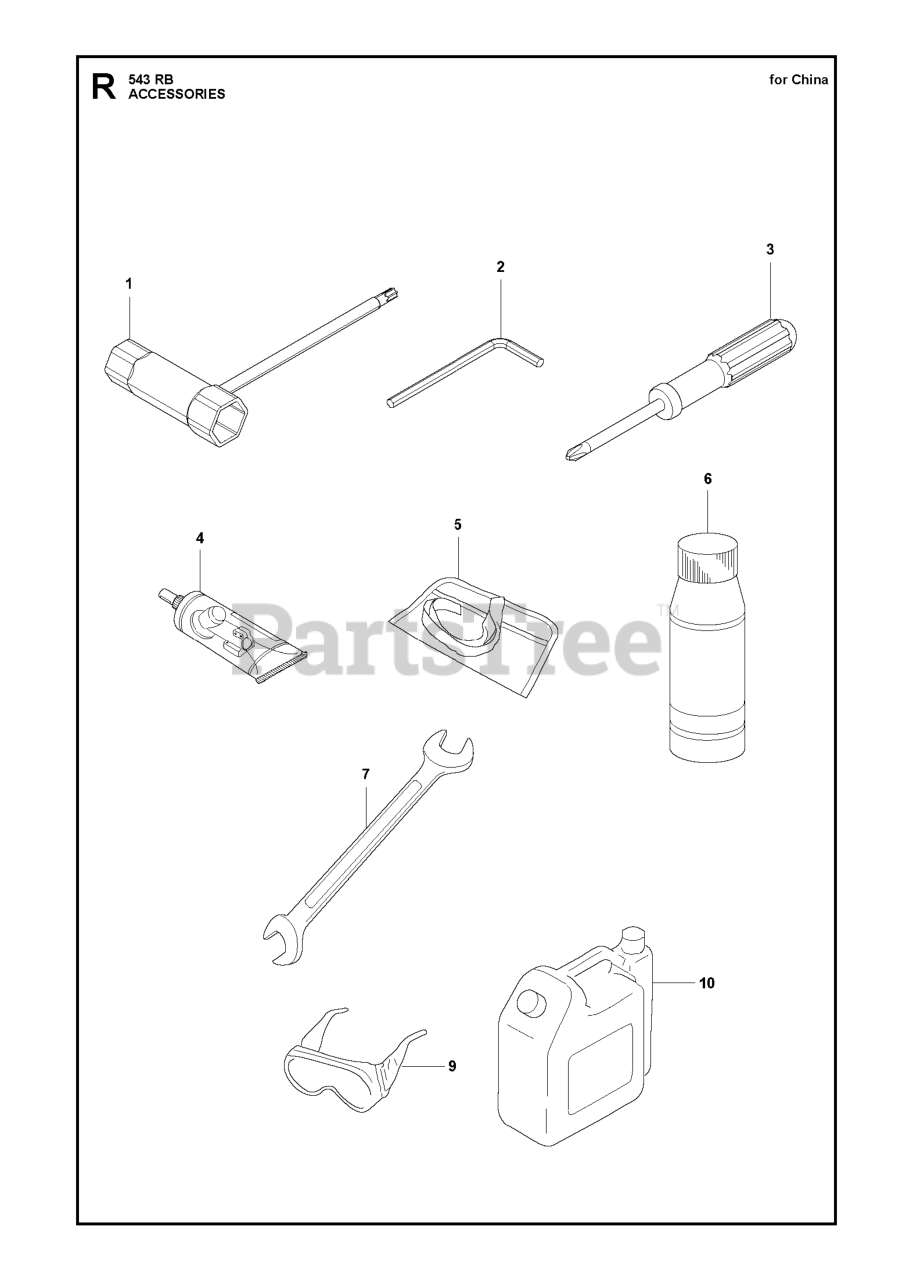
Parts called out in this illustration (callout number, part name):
1	SOCKET
2	WRENCH
3	DRIVER
4	BEVEL GEAR GREASE
5	TOOL BAG
6	Air Filter Oil 1l.
7	WRENCH SPANNER
9	GOGGLE
10	TANK
